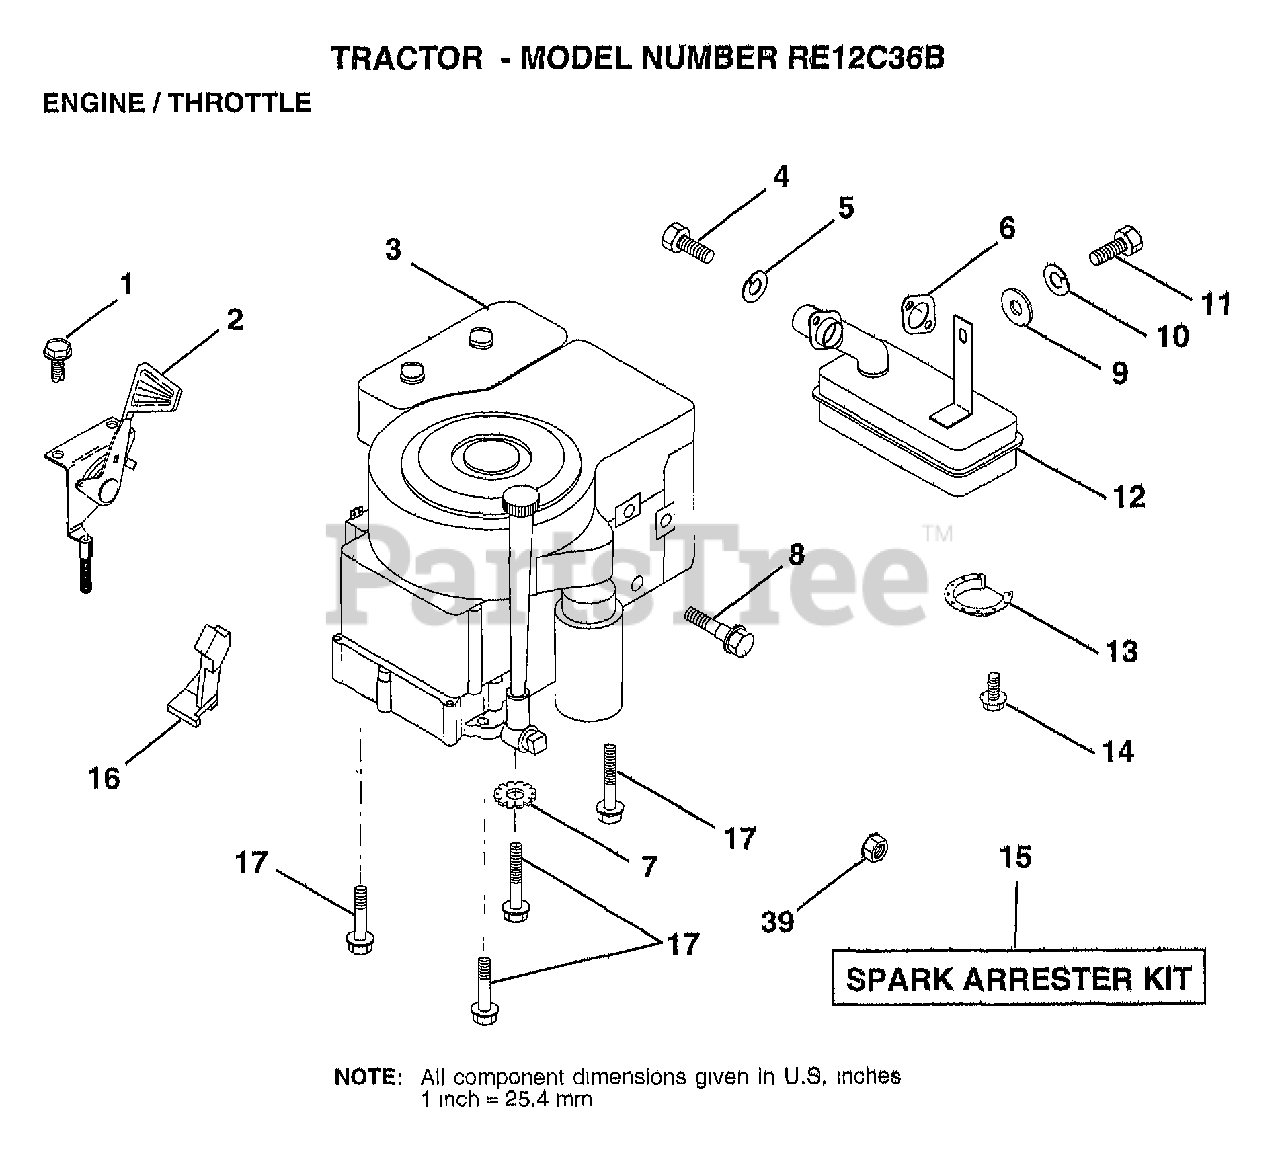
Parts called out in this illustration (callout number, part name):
1	SCREW.1/4-20X1/2
4	SCREW
5	LOCKWASHER
7	LOCKWASHER
8	BOLT T
10	LOCKWASHER
12	MUFFLER
13	DEFLECTOR.222573
16	"STOP,DASH THROTT"
17	SCREW LT
39	NUT
